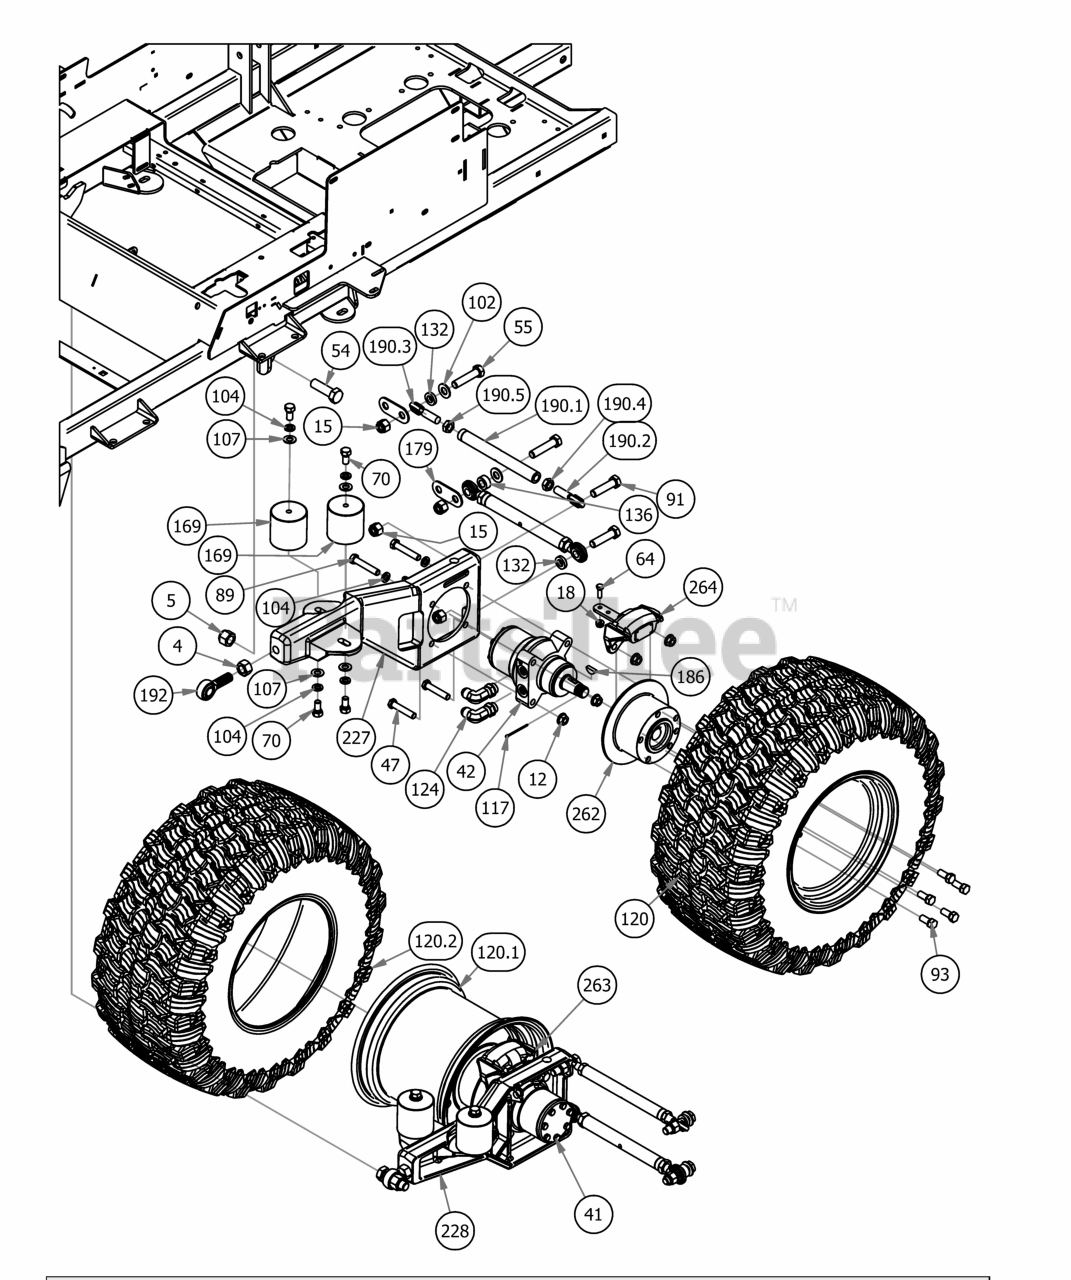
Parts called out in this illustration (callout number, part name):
4	3/4"-16 Fine Full Nut
5	3/4" Course Thread Nylon Lock Nut
12	1/2" Flange Nut
15	5/8 Std NC Nylock Nut
18	5/16-18 Nylon Flange Nut
41	18cc Parker Wheel Motor- Right
42	18cc Parker Wheel Motor- Left
47	1/2" x 3" Hex Bolt
54	3/4 x 2 1/2 Course Thread Bolt
55	AS 2465 - 5/8 x 2 3/4 UNC
64	5/16" x 1" Bolt
70	1/2" x 1" Hex Bolt
89	1/2" x 2 3/4" Hex Bolt
91	5/8" x 2 1/2" Grade 5 Hex Bolt (Coarse)
93	1/2-20 x 1-1/2 Lug Bolts Zinc
102	5/8" Flat Washer SAE Spec Grade 8
104	1/2" Lock Washer
107	1/2" Washer (Grade 8)
117	1/8x2-1/4 cotter pin Zinc
120	2019 Assy-26x12-12 Reaper Turf -10.5" Rim
120.1	2019 10.5" Wheel
120.2	2019 26x12-12 Reaper Turf Tire
124	2019 Rouge/Renegade Wheel Motor 90* Fitting #6801-10L
132	Spacer 1.125OD x .625 ID x .250 Length
136	5/8" x 1/" Collar W/One Set Screw
169	Vibration Mount-Blue Dot
179	2019 Suspension Gusset Outlaw
186	Woodruff Key
190	2019 Suspension Radius Rod Assembly
190.1	2019 Suspension Link Body
190.2	2019 RH 5/8" Heim
190.3	2019 LH 5/8" Heim
190.4	5/8-11 HEX JAM NUT ZINC
190.5	NUT, 5/8-18LH
191	2019 Suspension Radius Rod Assembly
191.1	Rear Radius Rod, 3/4 Body
191.2	3/4-16 x 5/8 RH Heim
191.3	3/4-16 x 5/8 LH Heim
191.4	3/4-16 HEX JAM NUT ZINC
191.5	3/4-16 LH HEX JAM NUT ZINC
192	3/4-16 RH Male Rod End
227	2019 Left Trailing Arm
228	2019 Right Trailing Arm
231	2019 Horizontal Diesel Frame
262	Brake Disk
263	XP/AOS Right Brake Caliper
264	XP/AOS Left Brake Caliper
